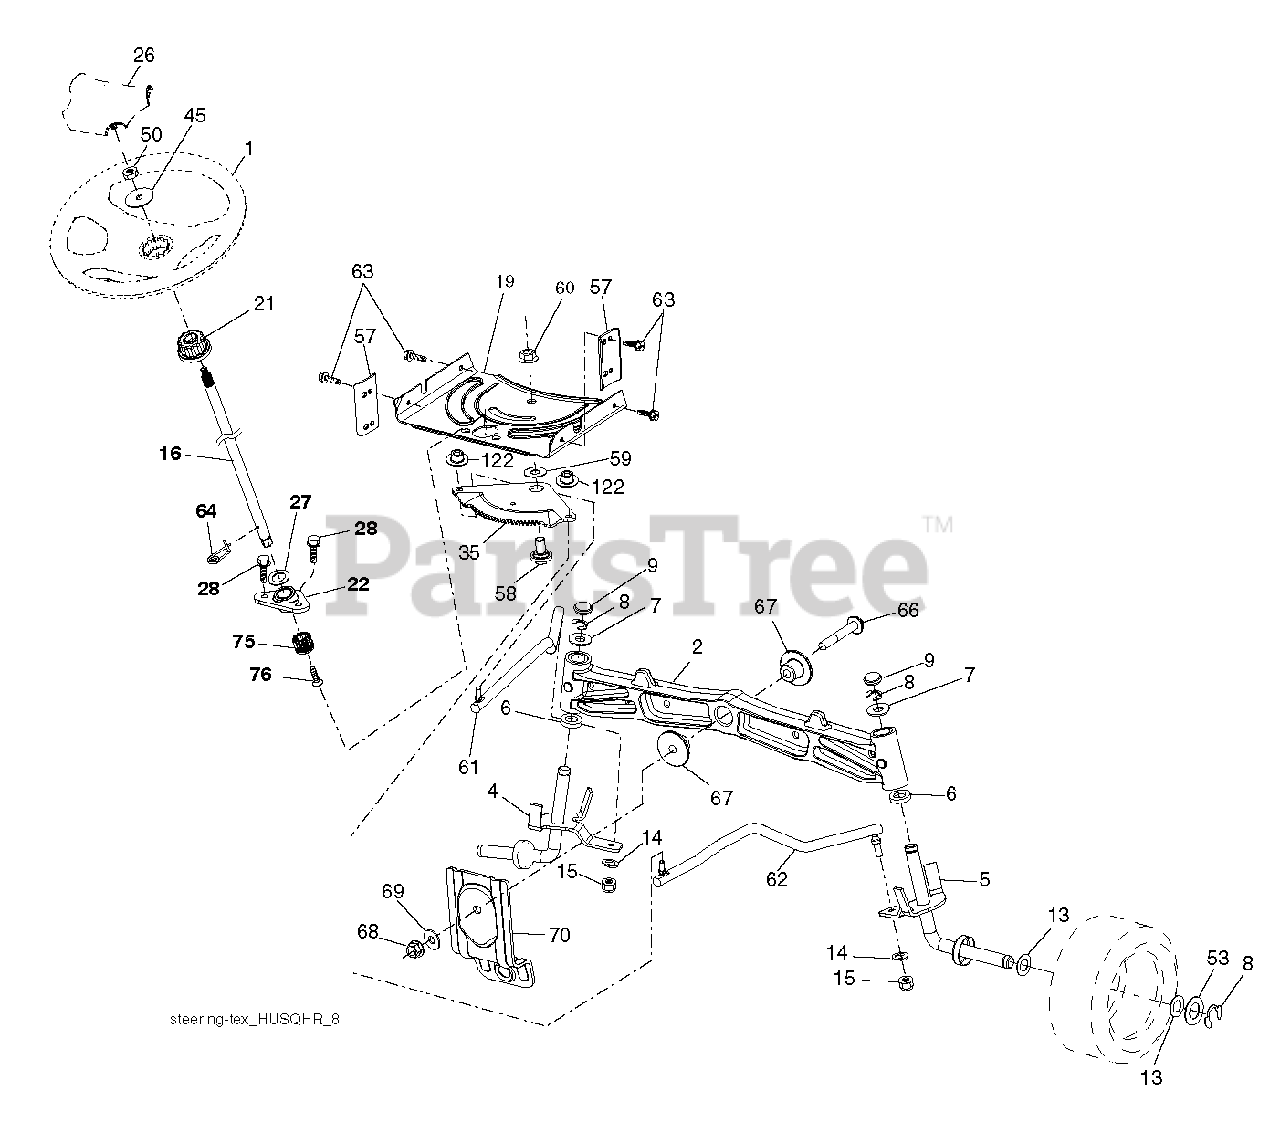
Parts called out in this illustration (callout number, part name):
1	WHEEL.STEER.HUSQ.SR.498.OVMLD
2	AXLE.CAST.IRON
4	SPINDLE.WELDED.LH.15"TEX
5	SPINDLE.WELDED.RH.15"T
6	THRUST WASHER
9	CAP.SPINDLE.BLACK
14	WASHER, LOCK 3/8
15	NUT CROWNLOCK 3/8-24
16	SHAFT.STEER.2HIGH.SPLND.PLATED
19	PLATE.STEER.DDL.NLT/NG
21	ADAPTER.WHEEL.STEER.SPLND.ALUM
22	BEARING.SHAFT.STEER.LOWER.625
26	INSERT.CAP.WHL.STRG.HUSQ.PREM
28	SCREW, 3/8-16X3/4
35	GEAR.SECTOR.PLATE.DDL.
45	WASHER.3/8ID.2-3/8OD.12GA.PLTD
50	NUT LOCK FLG 3/8-16 UNC
53	WASHER.HARDENED
57	BRACKET.UPSTOP.TEX
58	BOLT.SHOULDER.SECTOR.P
59	WASHER.THURST.SECTOR.S
60	NUT FLANGE LOCK 5/8-11
61	DRAGLINK.LH.BALLSTUD.D
62	DRAGLINK.RH.BALLSTUD.D
63	SCREW
64	RETAINER.CLIP.SPRING.S
66	BOLT HEX FGHD 7/16-14 X 3 SERR
67	BUSHING.PM.FRONT AXLE
68	NUT.LOCK.FLANGE.7/16
69	WASHER.1.5X.505X.118
70	BRACKET.FRT.DECK.SUSP.RR.MT431
75	PINION.ZINC PLATED
76	SCREW HEAD SOCKET LRVB
122	CAP.GEAR.SECTOR.TEX
